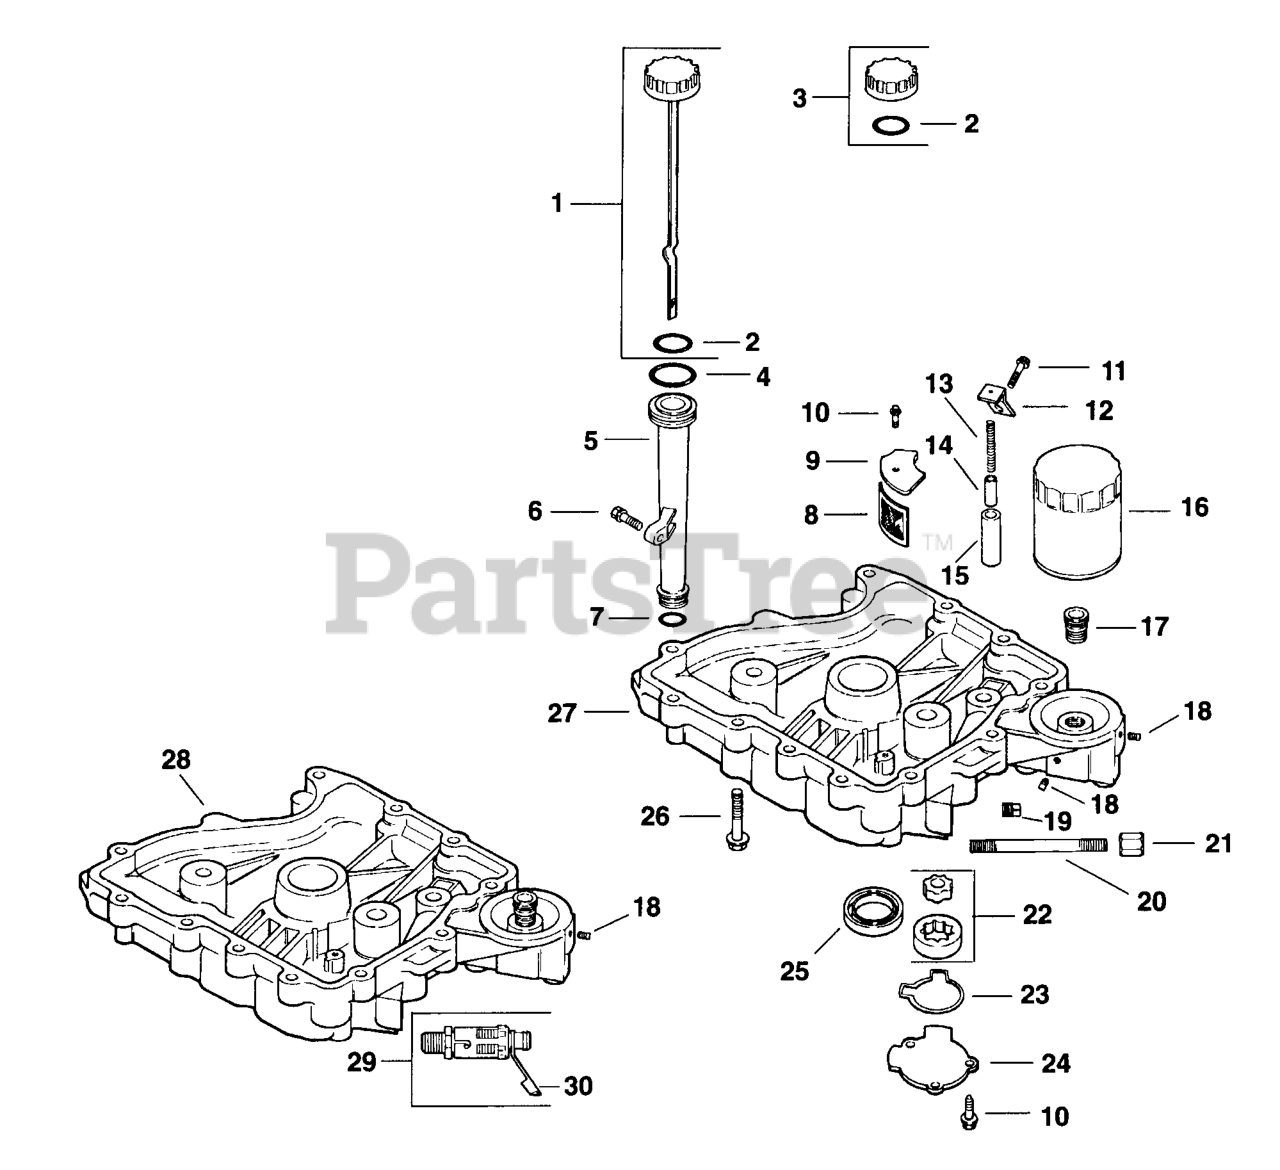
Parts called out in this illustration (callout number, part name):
1	Dipstick Assembly
2	O-Ring, Dipstick
3	Kit, Oil Fill Cap
4	O-Ring, Oil Fill Tube (Upper)
5	Tube, Oil Fill
6	Screw, Hex. Flange M5x0.8x20
7	O-Ring, Oil Fill Tube (Lower)
8	RING-HANDLE LOCK
9	Cover, Oil Pick-Up Screen
10	Screw, Hex. Flange M5x0.8x16
11	Screw, Hex. Flange M10x1.5x25
12	Bracket, Oil Pump Relief
13	Spring, Oil Pump Relief Valve
14	Piston, Oil Pump Relief Valve
15	Body, Oil Pump Relief Valve
16	Filter, Oil
17	Adapter, Oil Filter
18	Plug, Sq. Hd. Solid 1/8" N.P.T.F.
19	Plug, Sq. Hd. Solid 3/8" N.P.T.F.
22	Pump, Oil
23	O-Ring, Oil Pump Cover
24	Cover, Oil Pump
25	Seal, Oil (Pto End)
26	Screw, Hex. Flange M8x1.25x45
27	Pan, Oil
